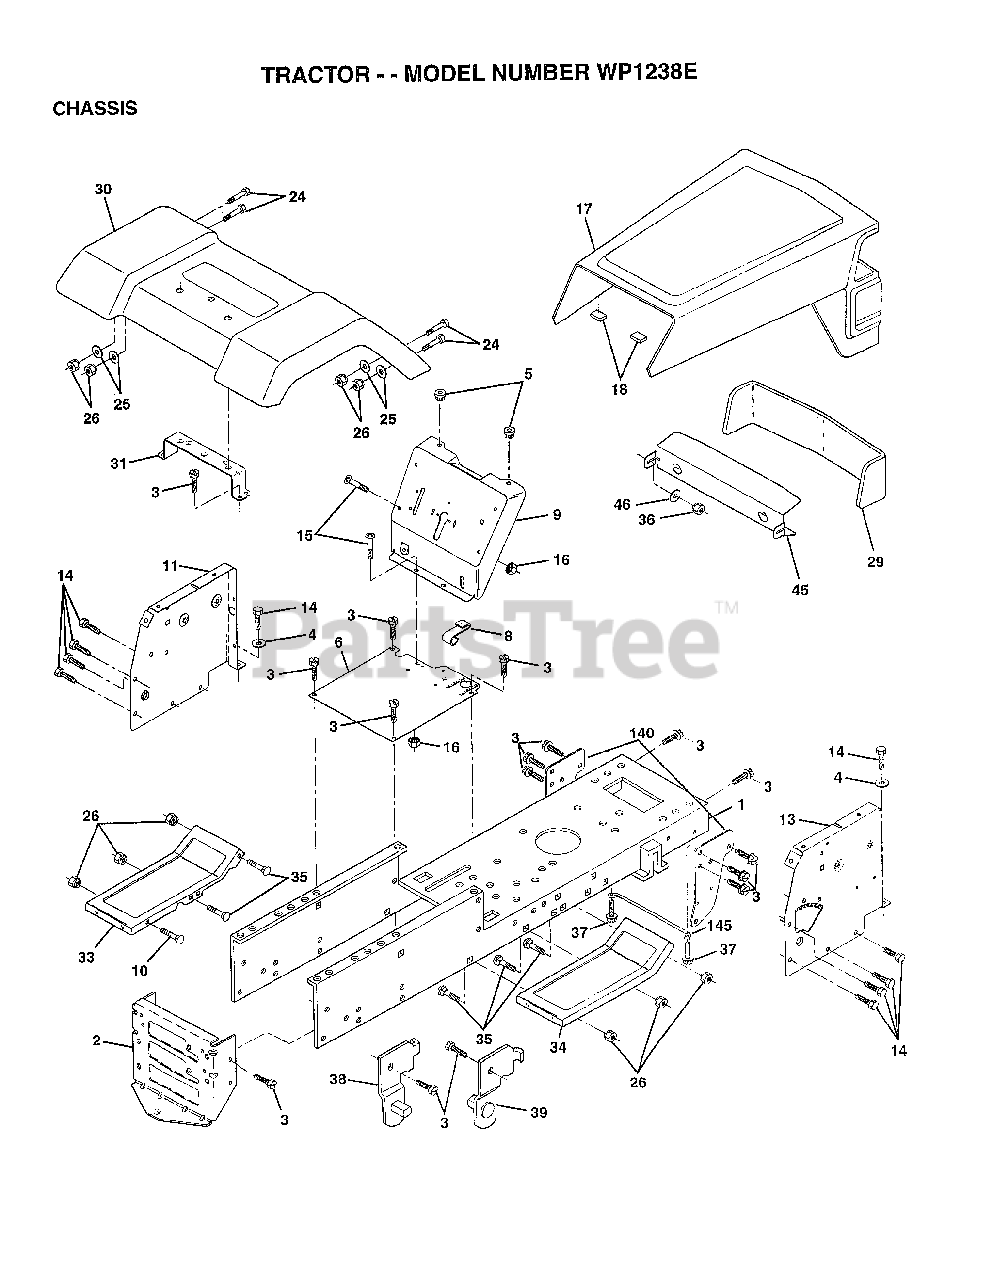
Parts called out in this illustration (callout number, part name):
3	SCREW
4	WASHER
5	BUMPER-HOOD/DASH
6	SADDLE-SILKSCREEN
8	CLIP.RETAINER
9	DASH.SILKSCREEN
11	"PANEL-DASH,LH"
14	SCREW LT
15	SCREW
17	HOOD/GRILL ASM
24	BOLT
25	WASHER
26	NUT
29	LENS SERVICE KIT
30	FENDER BRACKET
31	BRKT FENDER
33	FOOTREST LH
34	FOOTREST RH
35	BOLT
36	PAL NUT LT
38	BRACKET ASM LH
39	BRACKET ASM RH
46	RETAINER
140	BRKT SUSPENSION
145	"ROD POVOT,CHASSIS"
